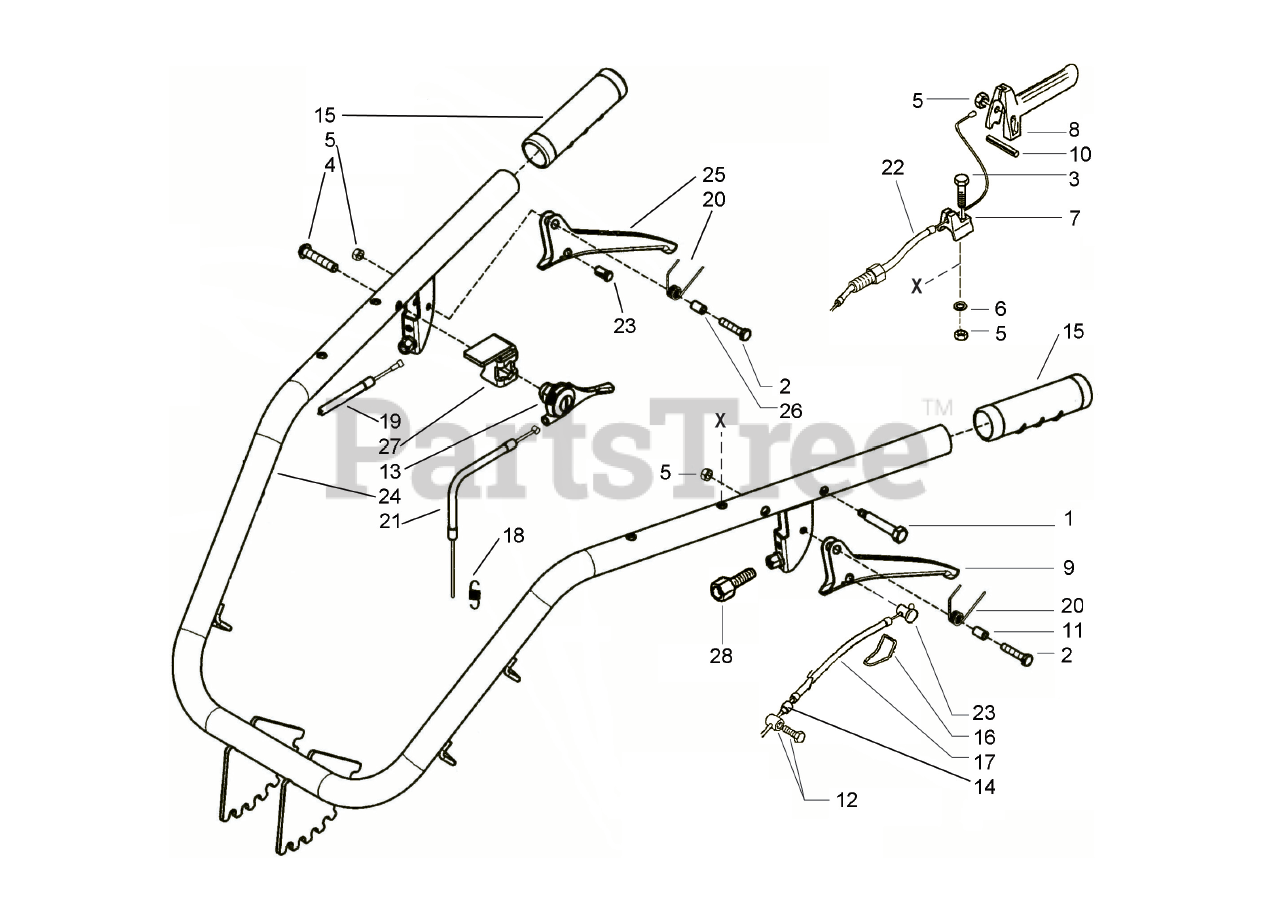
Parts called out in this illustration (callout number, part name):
1	CAP SCREW, M6 X 45
2	CAP SCREW, M6 X 25
3	CAP SCREW, M6 X 35
4	SCREW
5	LOCK NUT, M6
6	FLAT WASHER, M6
7	GUIDE, CABLE
8	LEVER, MOTOR STOP
9	LEVER, CLUTCH
11	LEVER, SPACER
12	CABLE CLAMP
13	LEVER. THROTTLE
14	SHEATH END
16	STOP WIRE
17	CABLE AND SHEATH, CLUTCH
18	SPRING
19	CABLE AND SHEATH, HANDLEBAR RELEASE
20	SPRING
21	CABLE & SHEATH, THROTTLE
22	CABLE, MOTOR STOP
23	BARREL
24	HANDLEBAR COMPLETE
26	SPACER
